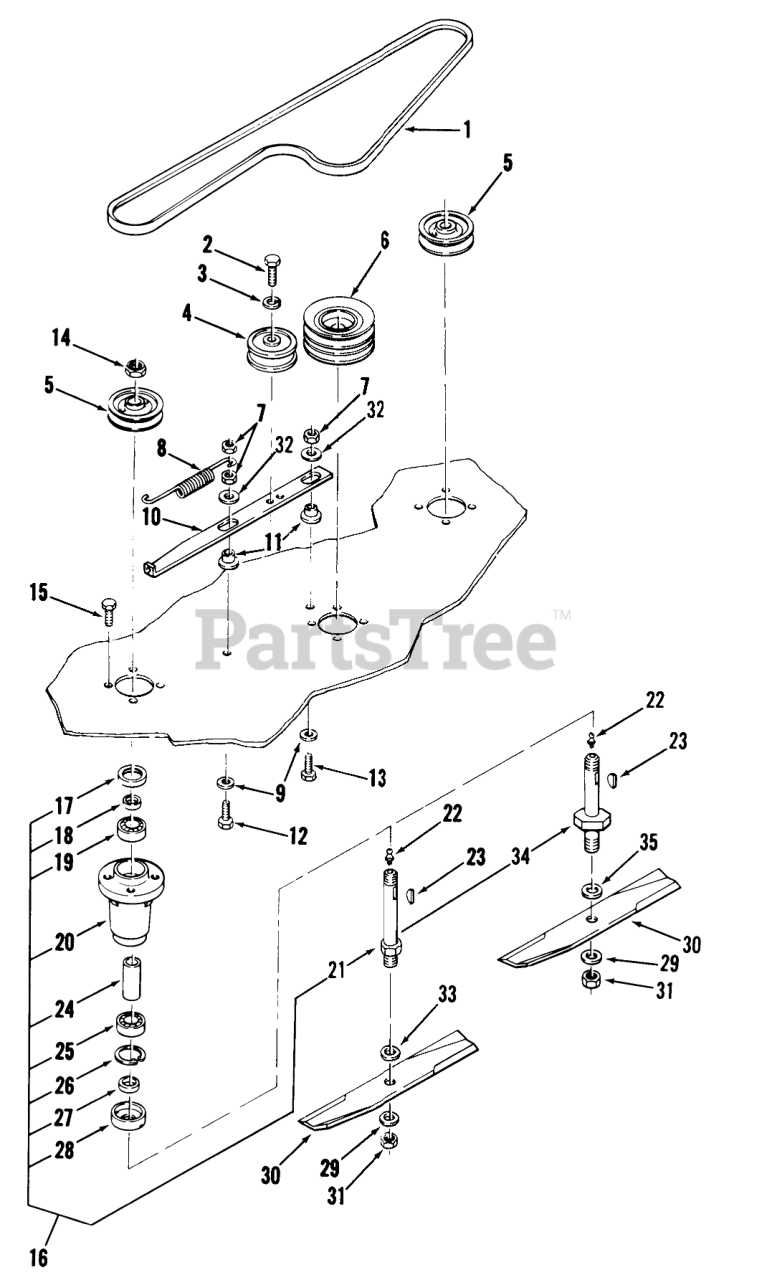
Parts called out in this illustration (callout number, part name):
1	V-BELT
2	BOLT HEX SPECIAL
3	LOCKWASHER
4	Idler Pulley
5	PULLEY-BLADE DRIVE
6	PULLEY-MOWER
7	NUT
8	SPRING-EXTENSION
9	WASHER
10	BAR-IDLER SUPPORT
11	SPACER-BUSHING
12	Bolt
13	Bolt
14	Nut
15	Bolt
16	Spindle Assembly
18	SPACER-SEAL
19	BEARING-BALL
20	HOUSING-SPINDLE
21	SPINDLE SHAFT ASM
22	Grease Fitting
23	Hi-Pro Key 3/16 x 5/8
24	SPACER
25	BEARING-BALL
26	Ring-Snap
27	SPACER-BLADE
28	CUP-SPINDLE
29	SpeciaI Washer
30	S/A BLADE KIT
31	Nut
32	WASHER
33	Washer
34	Spindle Shaft
35	SpeciaI Washer
